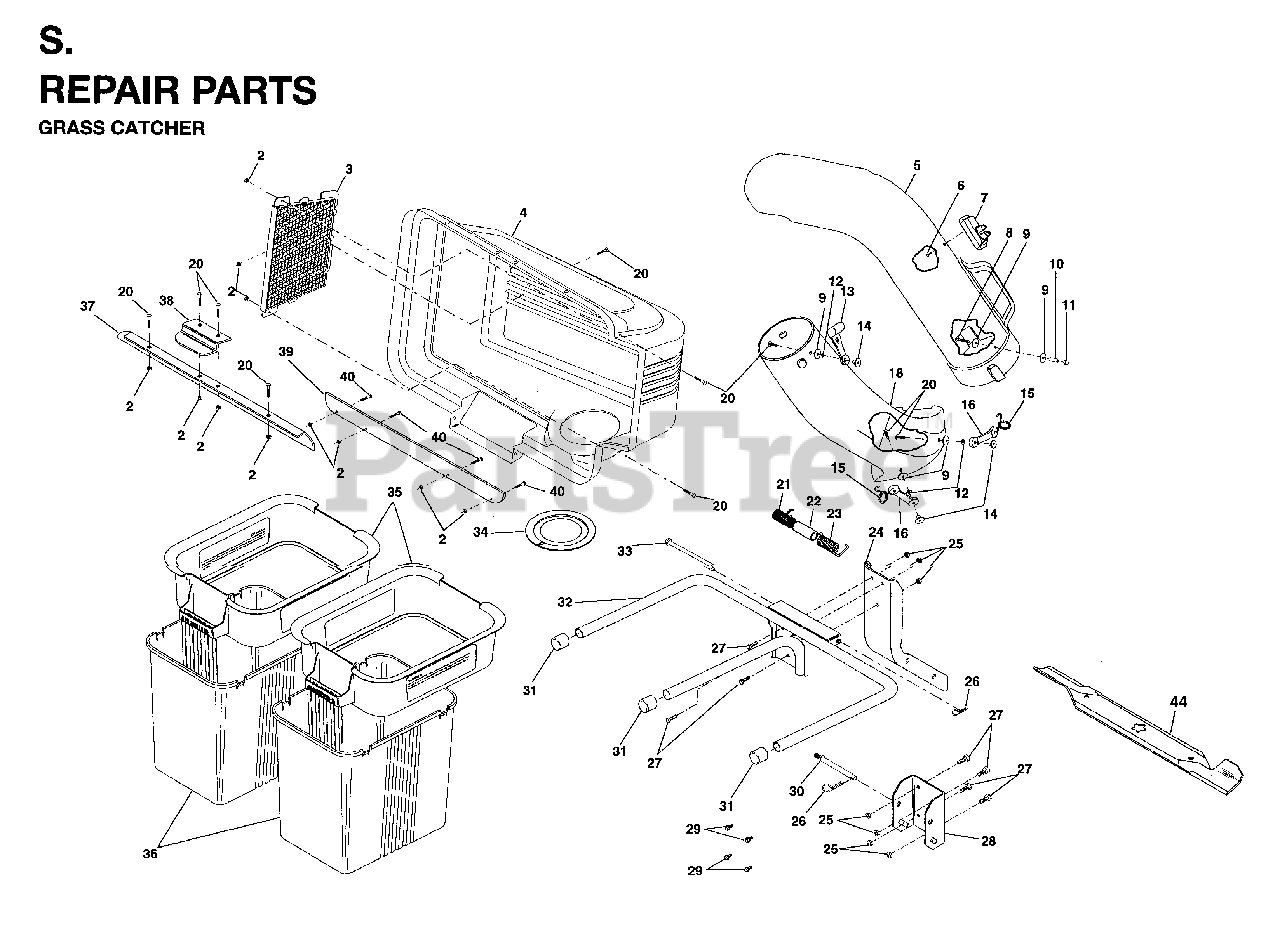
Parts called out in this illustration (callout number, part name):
3	COVER SCREEN
4	COVER BAGGER TOP
5	CHUTE.UPPER.42"
7	INDICATOR DUMP BAG
8	RP SCREW
10	SPACER LT
11	NUT
12	LOCKWASHER
13	HOOD LATCH T
14	NUT.WELD.#10-24
15	HOOK LATCH
16	RUBBER LATCH
18	CHUTE, LOWER
20	SCREW.10-24X5/8
21	SPRING COVER LH
22	SPACER.COVER.BAGGER
23	SPRING COVER RH
24	POST, SUPPORT
25	LOCKNUT
26	RETAINER SPRING
27	BOLT
28	MTG BRACKET
30	SUPPORT POST PIN
31	TUBING PLUG
32	BAGGER FRAME
33	HINGE PIN
34	GASKET COVER
35	CONTAINER TOP
36	CONTAINER BOTTOM
37	SEAL, COVER
38	LATCH CER38
39	SEAL STRIP
44	BLADE 42"
